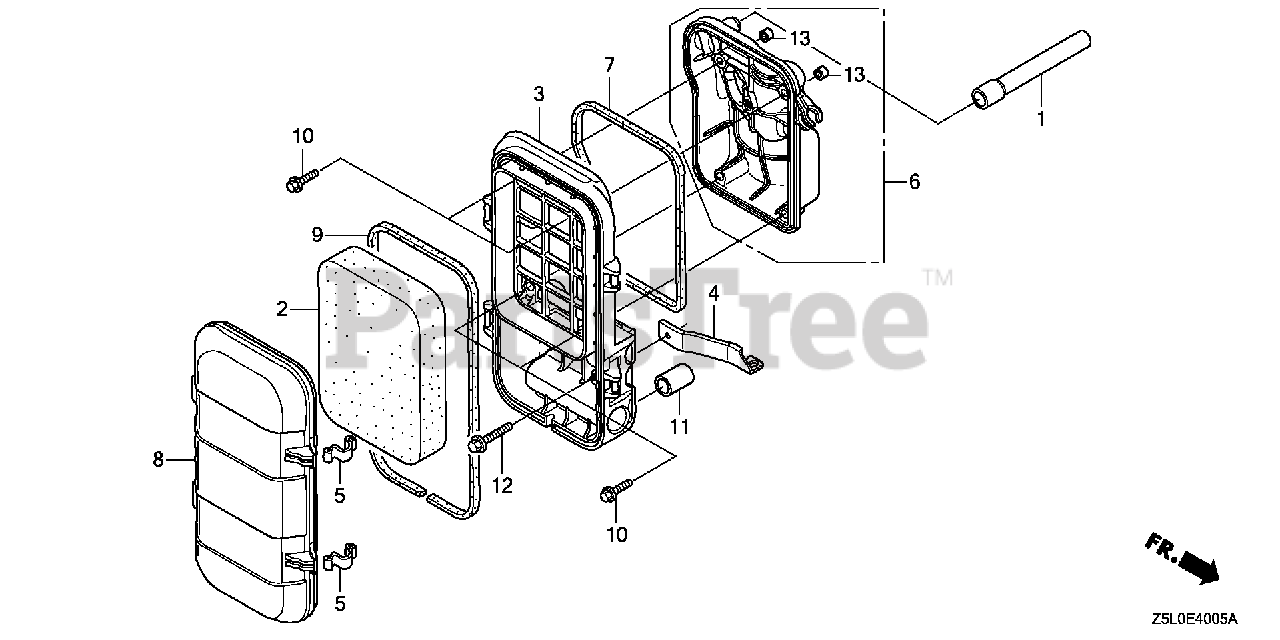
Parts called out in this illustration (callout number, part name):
1	TUBE, BREATHER
2	ELEMENT, AIR CLEANER
3	HOUSING, AIR CLEANER
4	STAY, AIR CLEANER
5	SPRING, AIR CLEANER HOUSING LID
6	BASE, AIR CLEANER
7	SEAL, AIR CLEANER HOUSING
8	COVER, AIR CLEANER
9	SEAL, AIR CLEANER COVER
10	BOLT, FLANGE (5X18)
11	CAP, SEALING
12	BOLT, FLANGE (6X32)
